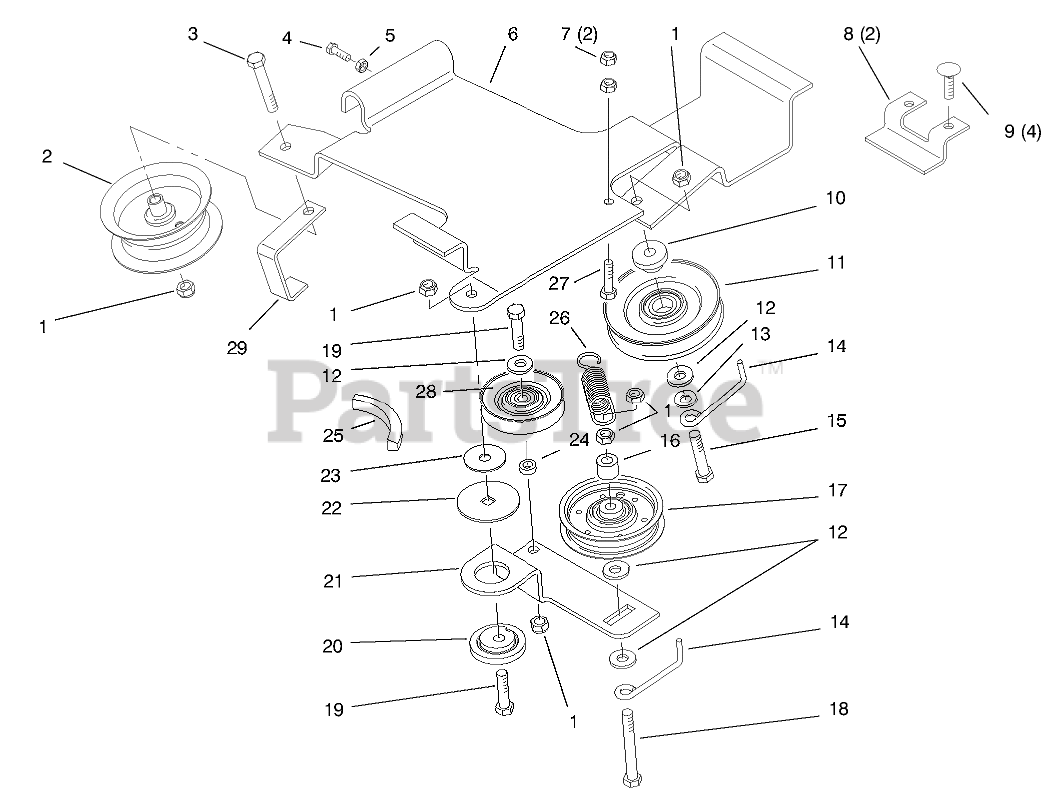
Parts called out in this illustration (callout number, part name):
1	NUT-LOCK, NI
2	IDLER
3	SCREW-HH
4	SCREW-HEX HD
5	NUT-JAM
6	RACK-TILLER DRIVE
7	NUT-LOCK, NI
8	BRACKET - RACK MOUNTING
9	BOLT-CARR
10	SPACER
11	PULLEY-IDLER
12	WASHER-SPACER
13	WASHER-FLAT
14	GUIDE-BELT
15	SCREW-HH
16	SPACER-PIVOT
17	PULLEY-IDLER, FLAT
18	SCREW-HH
19	SCREW-HH
20	BUSHING
21	ARM-IDLER
22	WASHER-BEARING
23	WASHER
24	Spacer
25	V-BELT
26	SPRING-EXTENSION
27	SCREW-HH
28	PULLEY-IDLER
29	Guide-Belt
